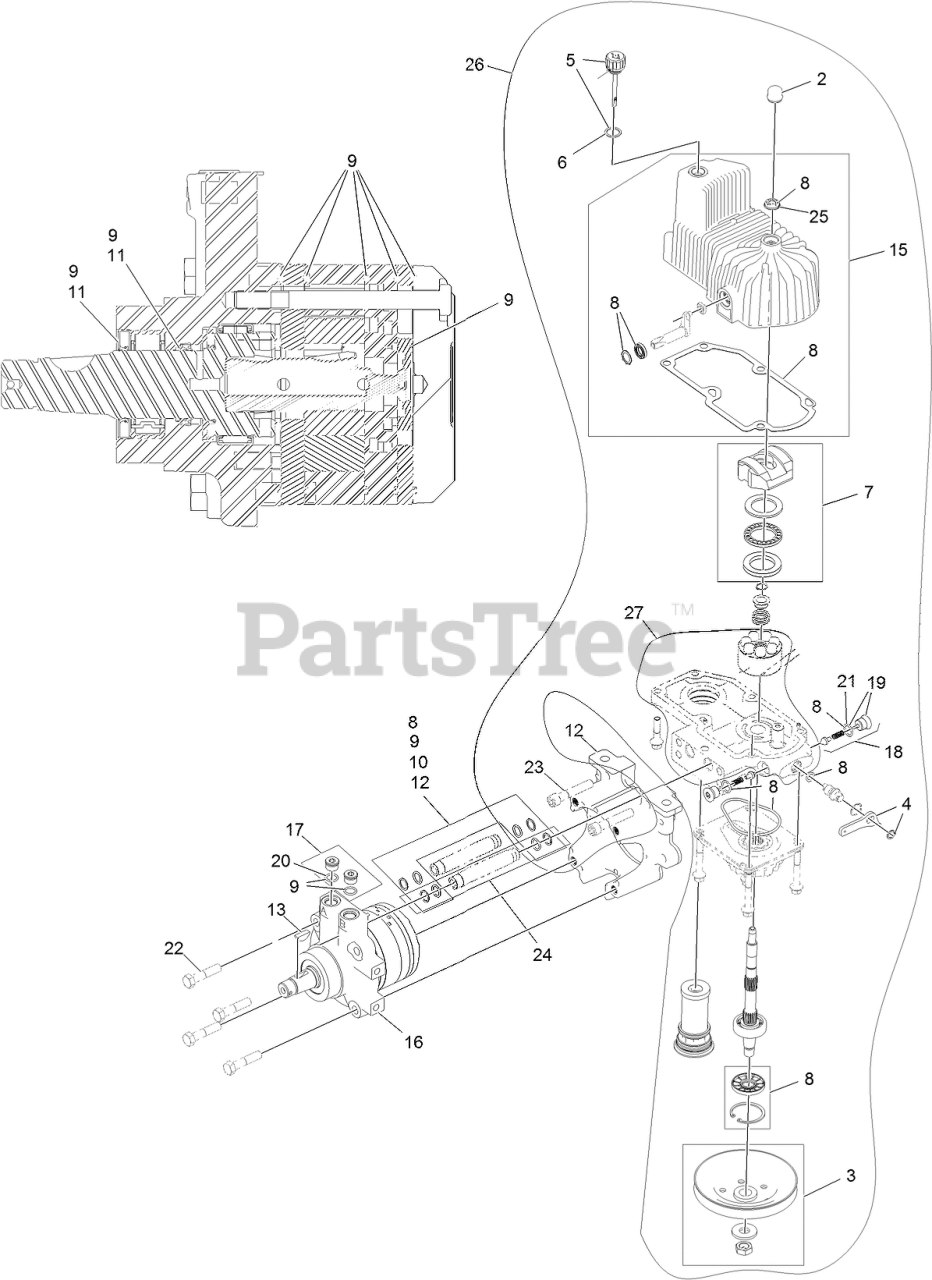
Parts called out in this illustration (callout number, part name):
2	COVER-SHAFT, HYDRO
3	PULLEY KIT
4	HANDLE-BYPASS VALVE, HYDRO
5	DIPSTICK-HYDRO W/GASKET
6	GASKET-DIPSTICK, HYDRO
7	SWASH BLOCK KIT
8	PUMP SEAL KIT
9	MOTOR SEAL KIT
10	TUBE SEAL KIT
11	OUTPUT SHAFT SEAL KIT
12	NOSE CUP-UHT
13	KEY-WOODRUFF
15	HOUSING-HYDRO, LH
16	MOTOR-HYDRAULIC LH 240CC
17	MAGNETIC PLUGS SERVICE KIT
18	CHECK VALVE ASM
19	PLUG-CHECK (W/O-RING)
21	O-RING-CHECK VALVE
22	SCREW HH
23	SCREW-HSH
24	HYDRAULIC TUBE KIT
25	SEAL-FAN DRIVE
26	FLOW TEST KIT
27	PULLER-PULLEY
